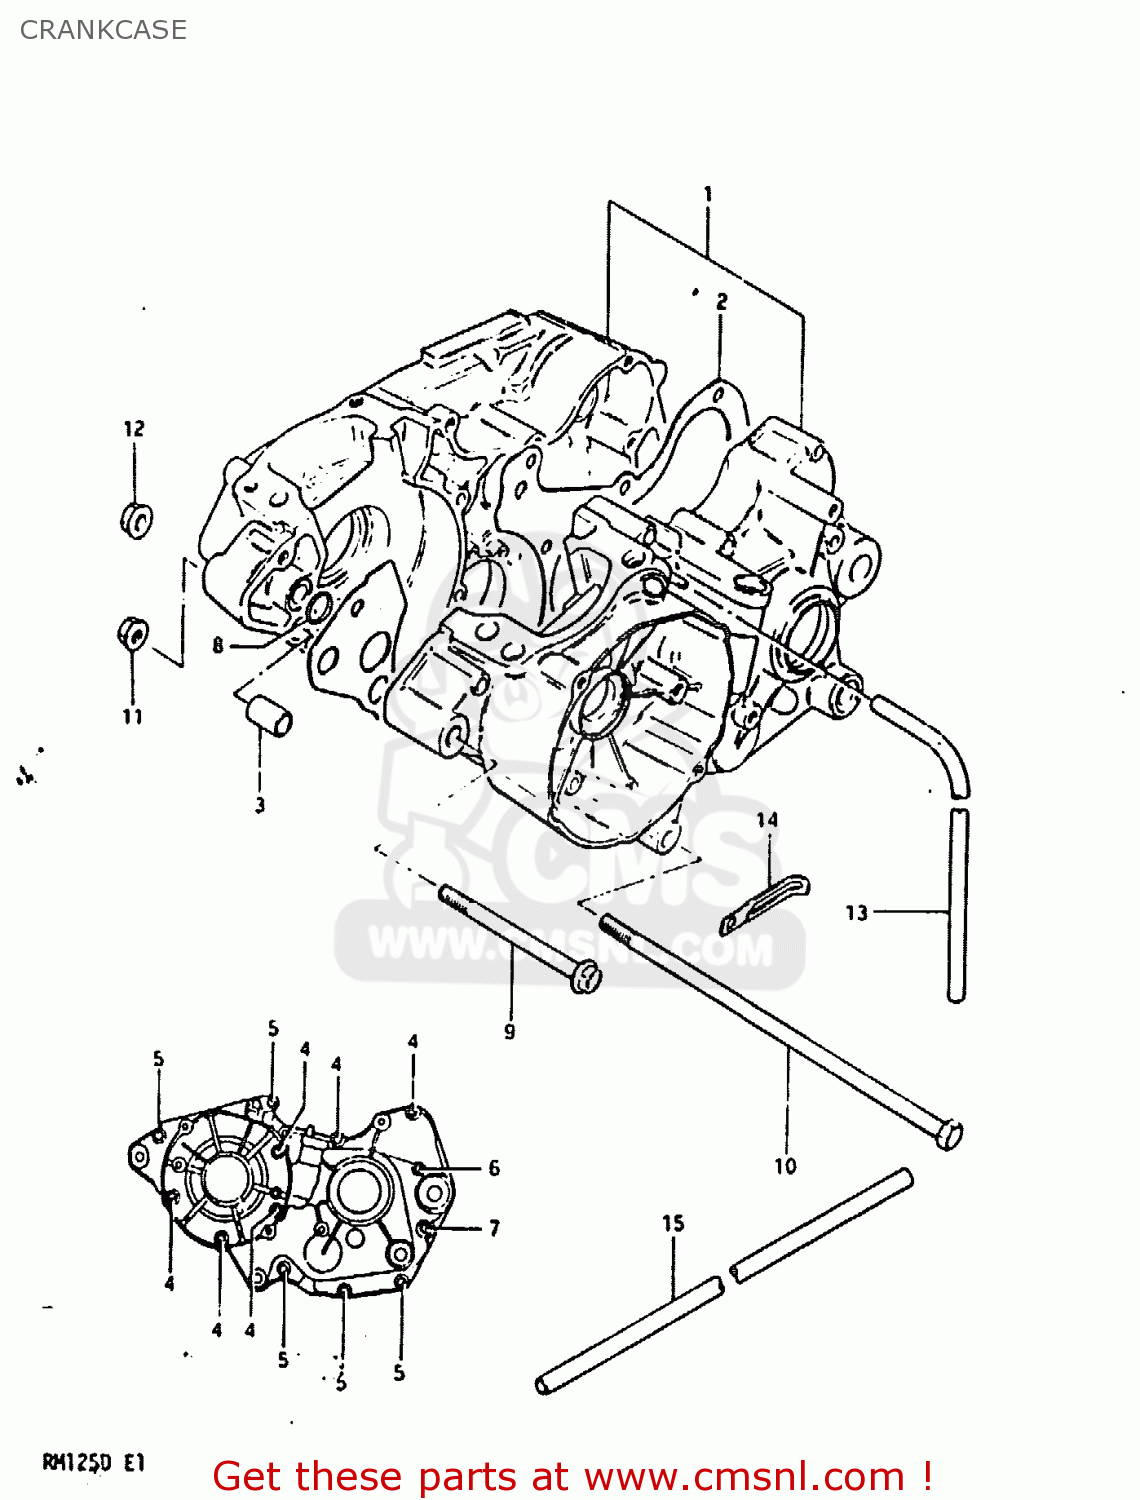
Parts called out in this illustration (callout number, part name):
1	CRANKCASE SET
2	GASKET,CRANKCASE (MCA)
3	PIN
4	SCREW (6X45)
5	SCREW
6	SCREW
7	SCREW 6X65
8	O RING(D:1.9,ID:13.8)
9	BOLT 8X90
10	BOLT 8X205
11	NUT
12	NUT
13	HOSE
14	CLAMP
15	HOSE
